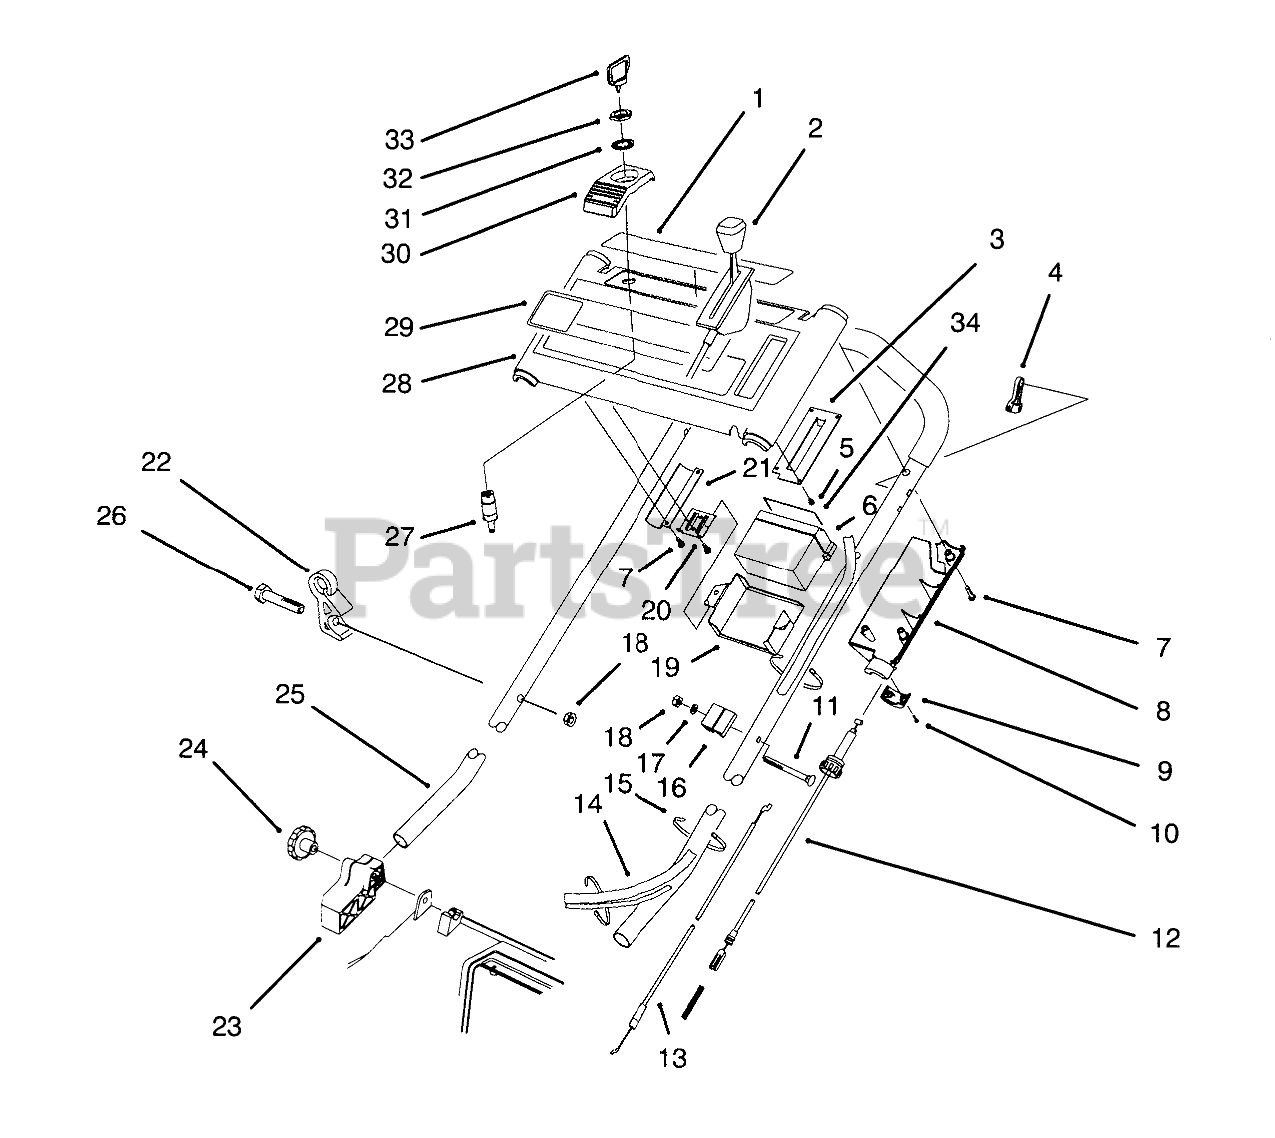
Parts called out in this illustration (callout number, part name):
1	DECAL - INSTRUCTION
2	CONTROL - THROTTLE
3	THROTTLE PLATE
4	LEVER-TRACTION
5	#6-19X.25 PLASK FORM SC
6	BATTERY ASSEMBLY
7	SCREW-PPH, PLASTITE
8	COVER-THROTTLE, LEVER
9	LOWER THROTTLE CAP
10	#4-14X.62 PLASTITE SCW
11	SCREW-HANDLE
12	CABLE - TRACTION
13	CABLE - BRAKE
14	Harness-Wire
15	TIE-CABLE
16	SUPPORT-CABLE
17	WASHER-FLAT
18	NUT-LOCK, NI
19	Retainer-Battery
20	BATTERY BRACKET
21	Bracket-Panel
22	GUIDE - ROPE
23	MOUNT-HANDLE, RH
25	HANDLE (DIPPED)
26	.250-20X1.625 HH SCREW
27	Switch-Starter (Incl. Ref. #31 & 32)
28	Panel-Control (Incl. Ref. #1 & 29)
29	DECAL - PANEL KEY
30	IGNITION SWITCH BRACKET
31	WASHER-TOOTH, INTERNAL
32	NUT-HH
33	KEY-IGNITION
34	DECAL-BATTERY
